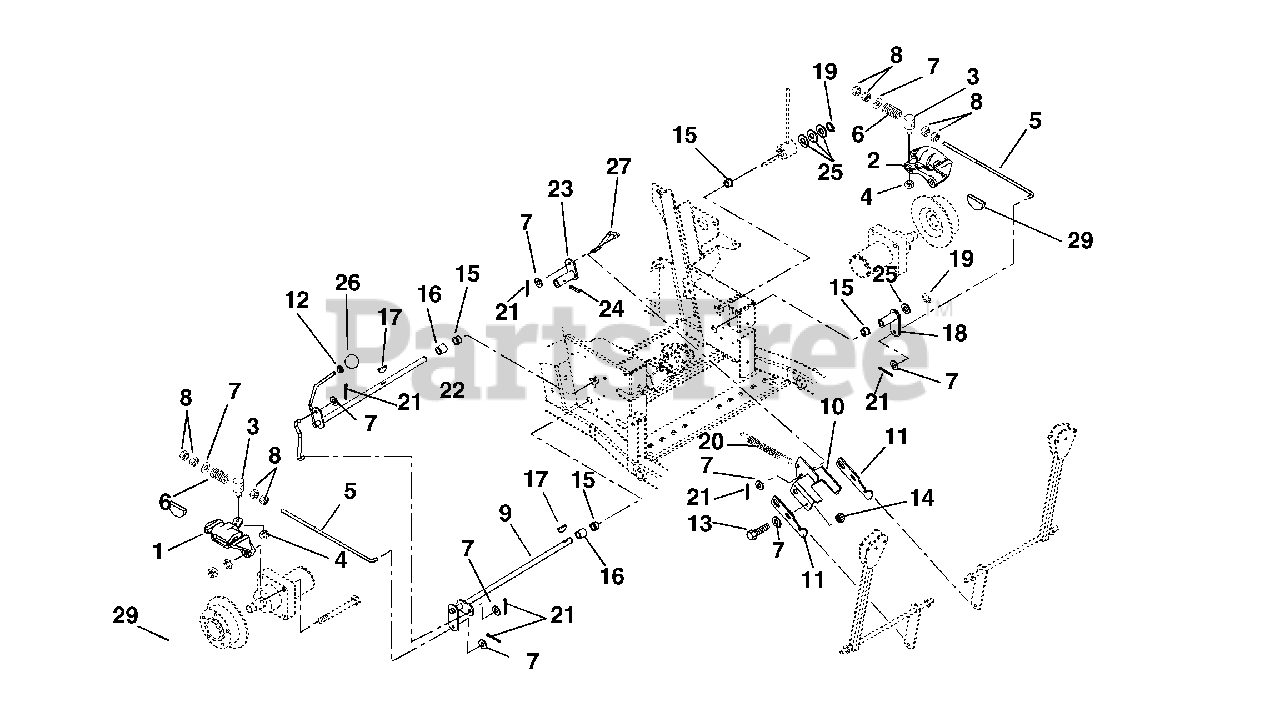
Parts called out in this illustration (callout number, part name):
1	Caliper, Park Brake (CW) Right Hand
2	Caliper, Park Brake (CCW) Left Hand
3	Pivot-Brake Rod
4	Nut-Locking-Center .31-18
5	Rod-Brake 12 inch
6	Spring-Compression .143 x .710 x 2.00
7	Washer-Flat-Steel .406 x .812 x .065
8	Nut-Hex .38-16
9	Shaft-Brake Cross
10	Interlock-Fixed
11	Interlock-Adjustable
12	Nut-Hex-Jam .375 -16
13	Bolt-Hex .38-16 x 1.00 Grade 5
14	Nut-Locking-Center .38-16
15	Bushing-Flange .630 x 1.000 x .625
16	Spacer .630 x .878 x 1.000
17	Key-Woodruff .19 x .75 Hard #9
18	Arm-Brake Left-Hand
19	Ring-Retaining-External .625 x .050
20	Spring-Tension .105 x .85 x 5.00
21	Pin-Cotter External .09 x .75
22	Shaft-Brake Actuating
23	Actuator
24	Pin-Roll .125 x 1.00
25	Washer-Flat-Steel .627 x .990 x .032
26	Knob-Steering Lock
27	Rod-Brake Actuating
28	Pin-Cotter-External .09 x .75 r
29	Pad, Disk Brake
